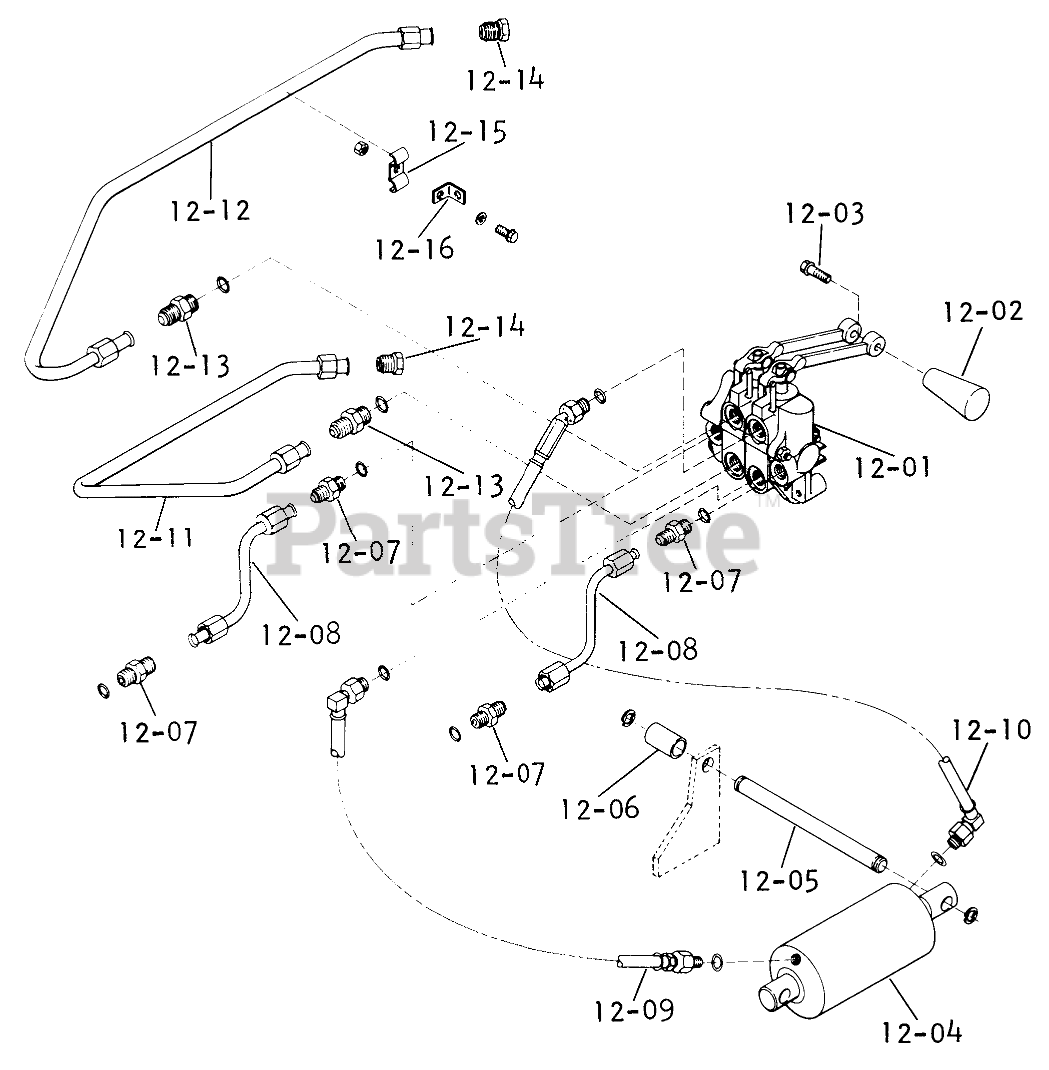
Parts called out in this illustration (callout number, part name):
12-01	Valve Assy.
12-03	Bolt-Hex 1/4-20 x 7/8
12-04	Cylinder
12-05	Cylinder Pivot
12-06	Spacer
12-07	FITTING
12-08	PRESSURE TUBE ASSY
12-09	Ass-y . Hose-14 1/2
12-10	Hydraulic Hose Assy
12-11	Front Tube Assy
12-12	Rear Tube Assy
12-13	FITTING
12-15	Clamp Tube
12-16	Clip-Spring Retainer
